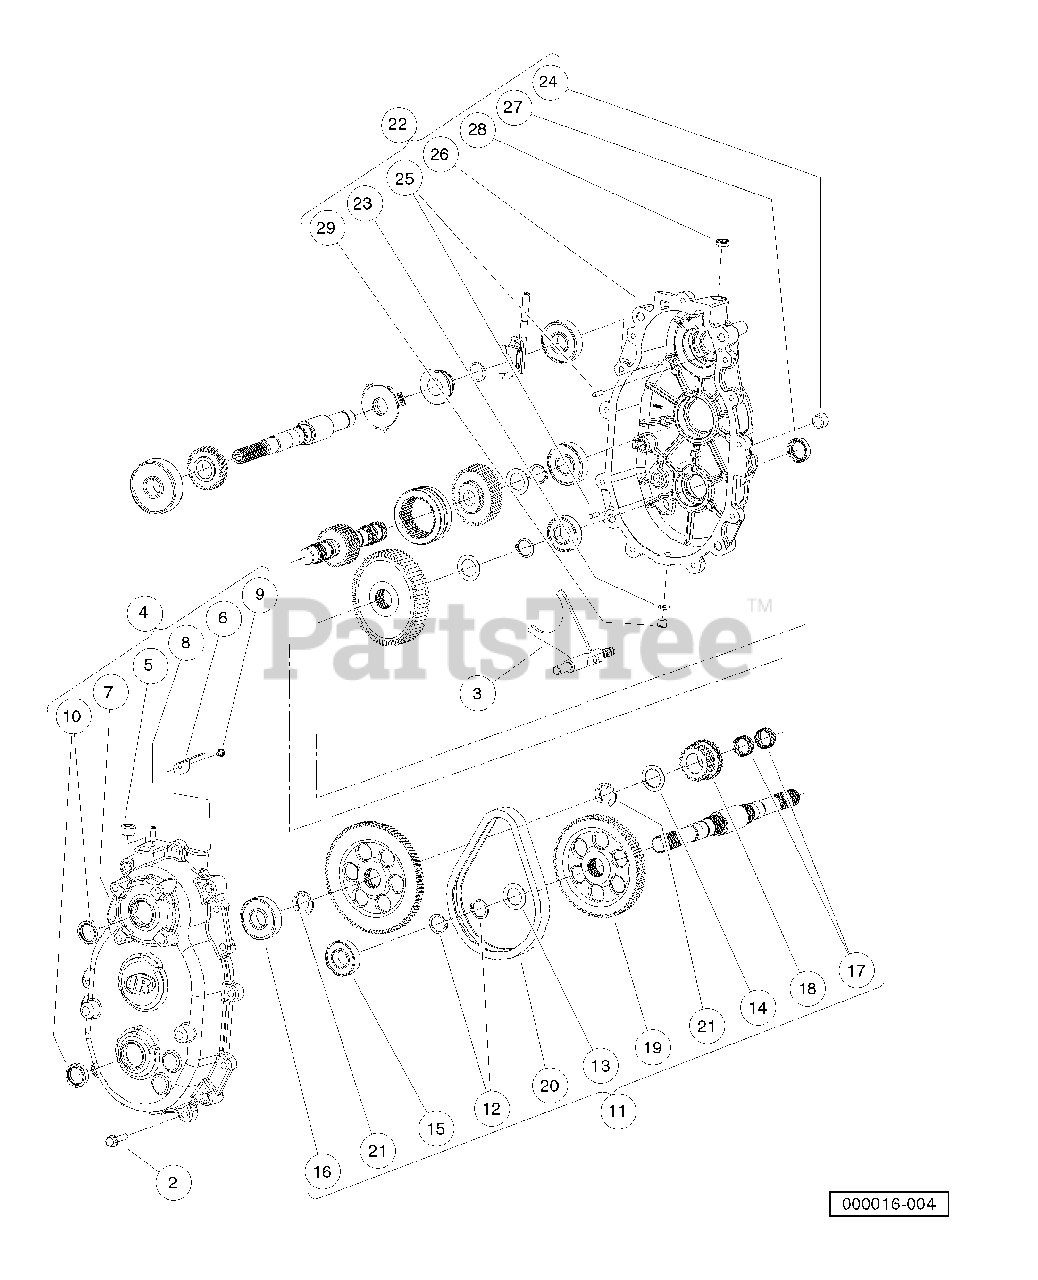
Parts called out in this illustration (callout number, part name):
1	Transmission, Parallel Shaft
2	Screw,hex Flange, M8 X 35
3	Fork, Transmission
4	Asm, Gear Case, Rear
5	Plug, Square Skt, 1/12-14, Ptf
6	Oil, Deflector
7	Gearcase, Rear
8	Vent, Trans
9	Screw, Tapping # 10-24 X .375
10	Seal, Triple, 25 X 35 X 7.8
11	Kit, Reverse Gear Repair
12	Ring, Retaining, Basic External
13	Washer, Thrust, 1.007 X .062
14	Washer, 26.231 X 39.167 X 1.57
15	Bearing, Ball
16	Bearing, Ball
17	Bearing, Needle
21	Ring, Retaining, E-Ring
22	Asm, Case, Gear, Front
23	Washer, .625 X .382 X .60
24	Plug, Square Skt, 1/12-14, Ptf
25	Pin, Dowel, 6 X 20
26	Gearcase, Front
27	Seal, Triple, 25 X 35 X 7.8
28	Seal, Dual-Lip
29	Plug, 3/4-16
